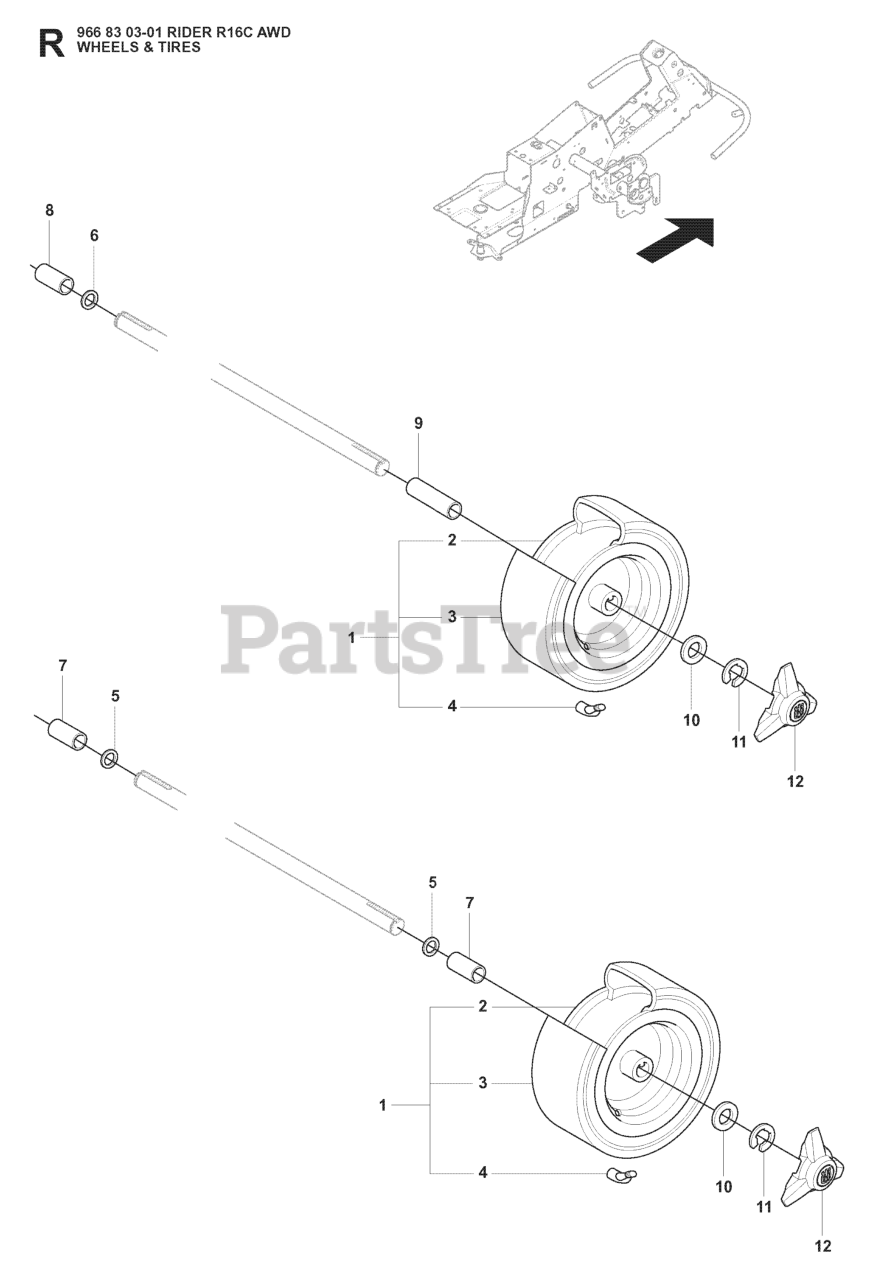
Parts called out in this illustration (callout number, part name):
1	WHEEL
2	RP RIM
7	SPACE SLEEVE
11	RETAINING RING
